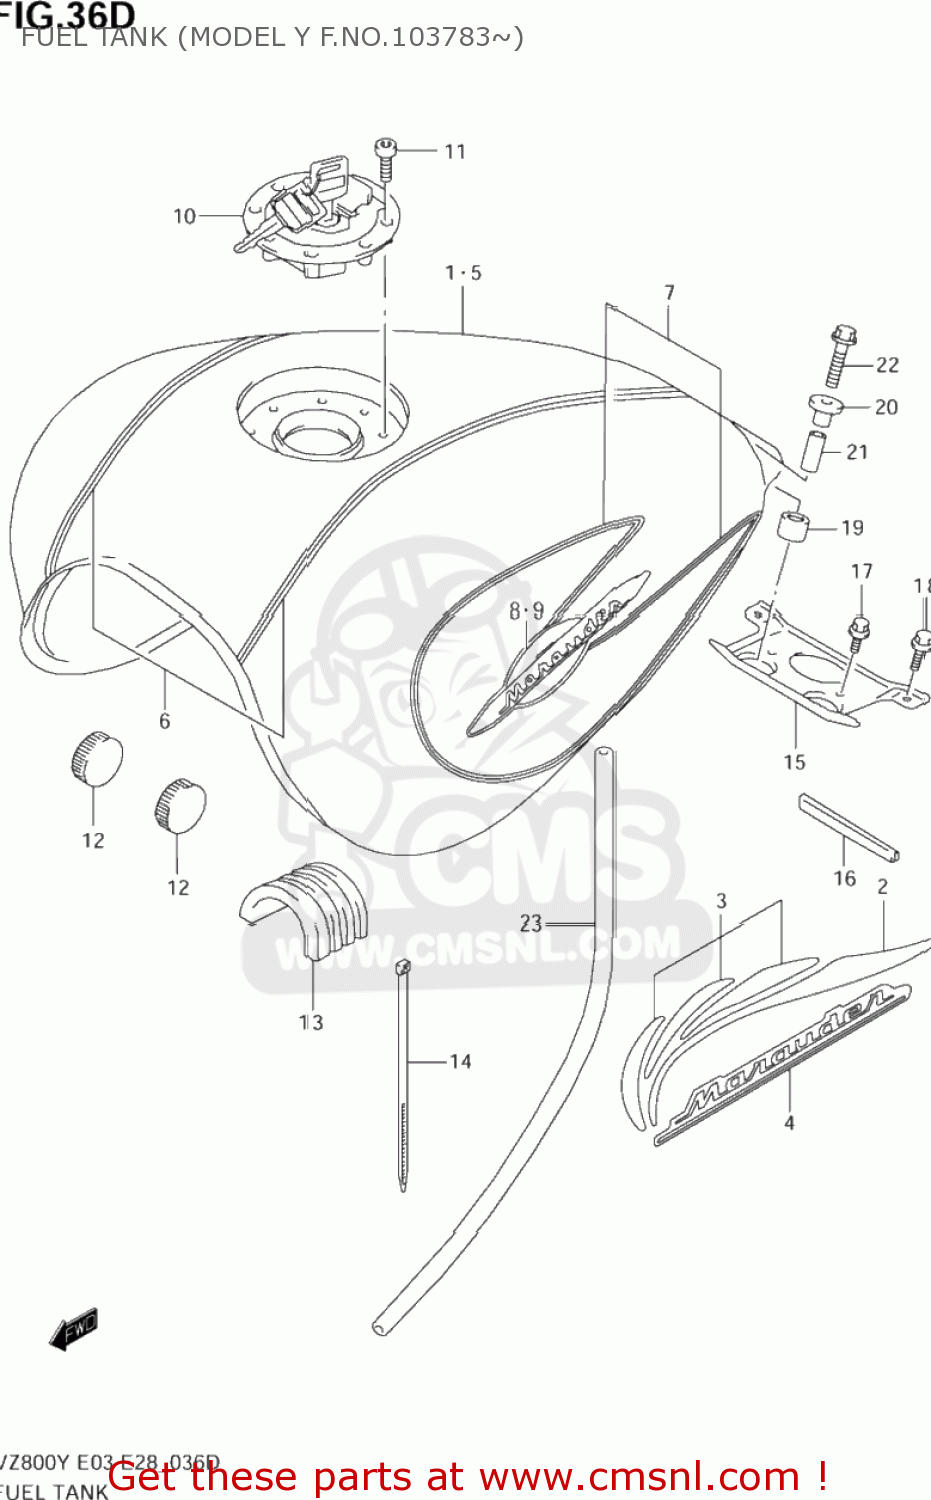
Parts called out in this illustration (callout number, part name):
1	TANK ASSY,FUEL(BLACK)
2	TAPE SET,FUEL TANK (SILVER)
3	EMBLEM SET,FUEL TANK
4	EMBLEM,FUEL TANK
5	TANK SET,FUEL
6	TAPE SET,FUEL TANK
7	TAPE SET, SIDE E28
8	EMBLEM,FUEL TANK,R
9	EMBLEM,FUEL TANK,L
10	CAP SET,FUEL TANK
11	BOLT(5X20)
12	CUSHION
13	CUSHION,FUEL TANK UPR
14	CLAMP(L:250)
15	BRACKET,FUEL TANK RR
16	PROTECTOR
17	BOLT
18	BOLT
19	CUSHION,FUEL TANK RR NO.2
20	CUSHION
21	SPACER(6.5X10.5X22.5)
22	BOLT
23	HOSE,FUEL TANK DRAIN
